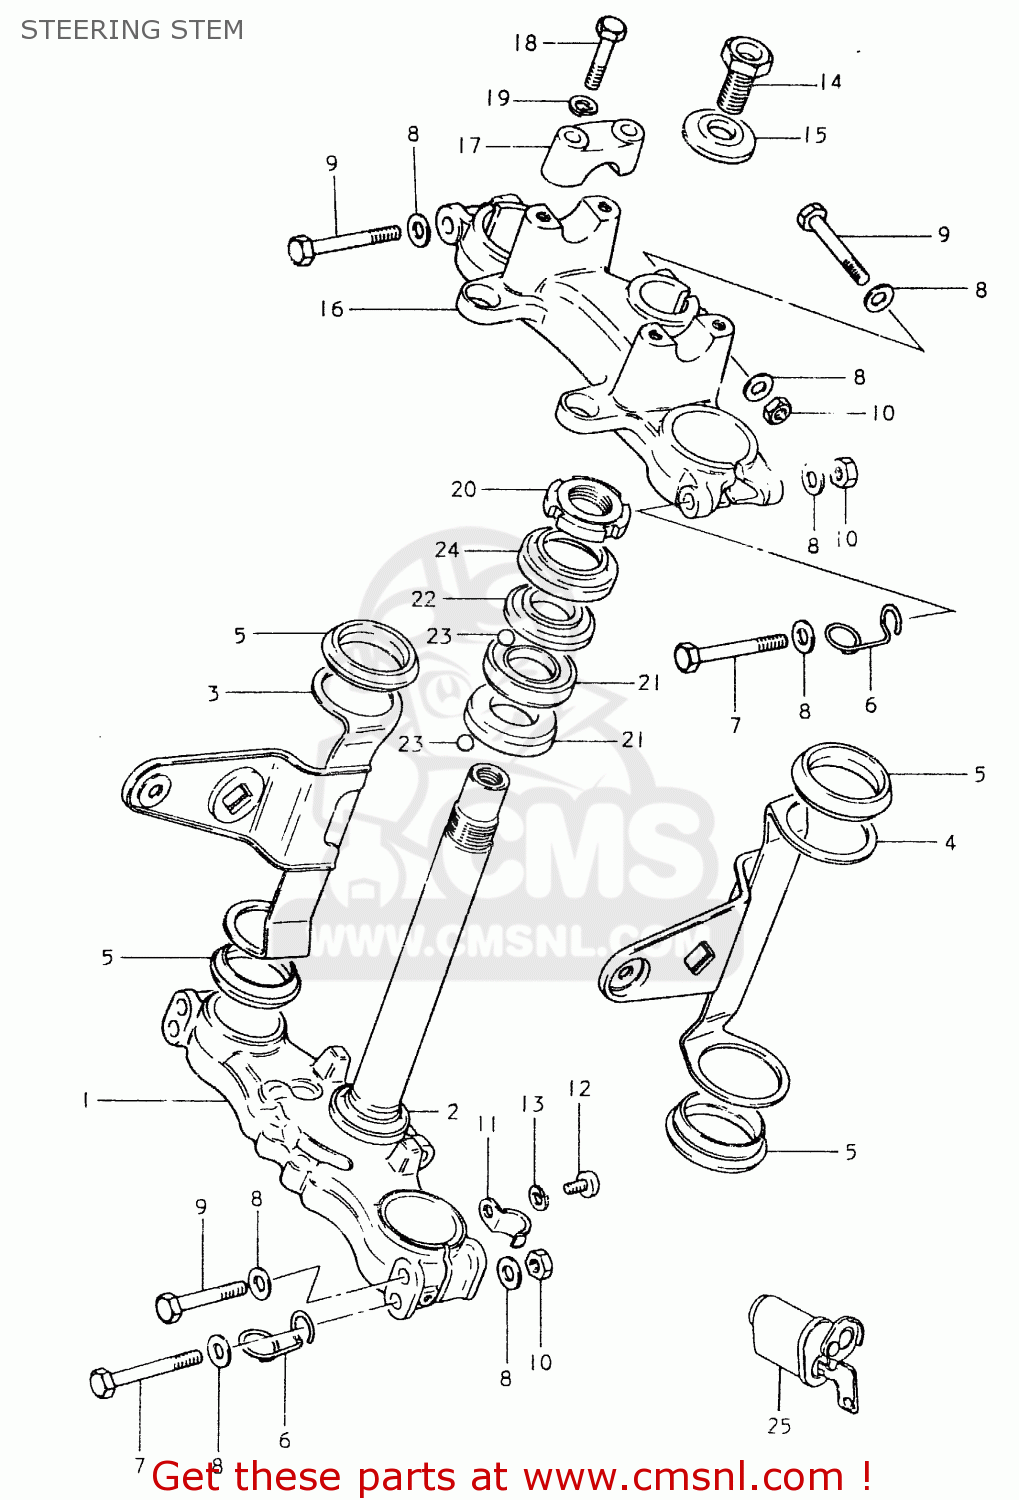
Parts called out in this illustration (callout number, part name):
1	STEM,STEERING
2	RACE,STEERING OUTER LWR
3	BRACKET,HEADLAMP,RIGHT
4	BRACKET,HEADLAMP,LEFT
5	CUSHION,HEADLAMP BRACKET
6	GUIDE,CABLE
7	BOLT
8	WASHER
9	BOLT 8X55
10	NUT
11	CLIP,BRAKE CABLE
12	SCREW
13	LOCK WASHER
14	BOLT,STEERING STEM HEAD
15	WASHER
16	HEAD,STEERING STEM
17	HOLDER,HANDLEBAR
18	BOLT
19	LOCK WASHER
20	NUT,STEERING STEM(25X44X10)
21	LACE,STEERING INNER LWR
22	LACE,STEERING OUTER UPR
23	BALL
24	DUST SEAL,STEERING UPR
25	LOCK ASSY, STEERING (NEIMAN TYPE EXECUTE
